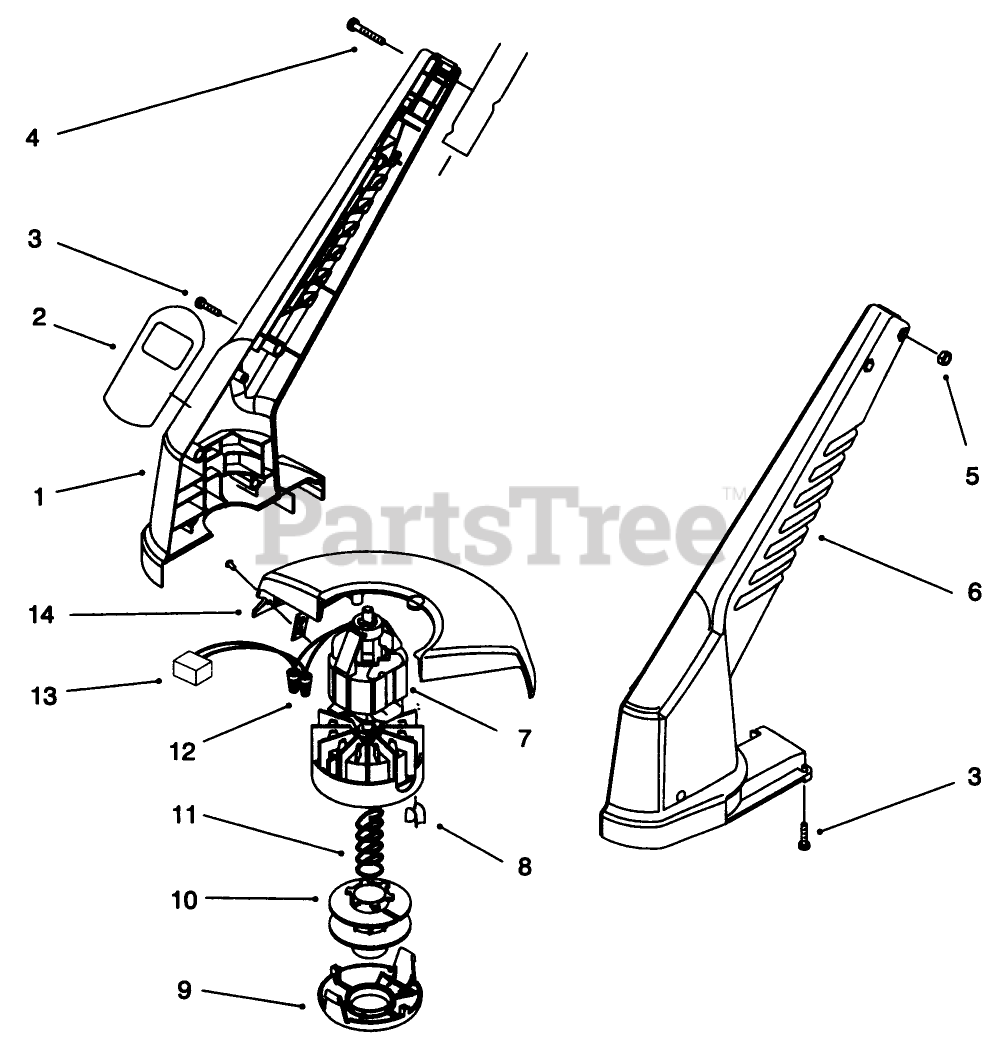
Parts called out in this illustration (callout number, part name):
1	HOUSING RH - TRIMMER, EUO
2	Decal-35CM Trimmer
3	SCREW-PPH
4	SCREW-PPH
5	NUT-HEX
6	HOUSING LH - TRIMMER
7	Motor-Trimmer (Incl. Ref. #8)
8	EYELET
10	SPOOL-LARGE
11	SPRING-COMPRESSION
12	CONNECTOR-NUT, WIRE
13	FILTER - RFI
14	SHIELD ASM - SERVICE
